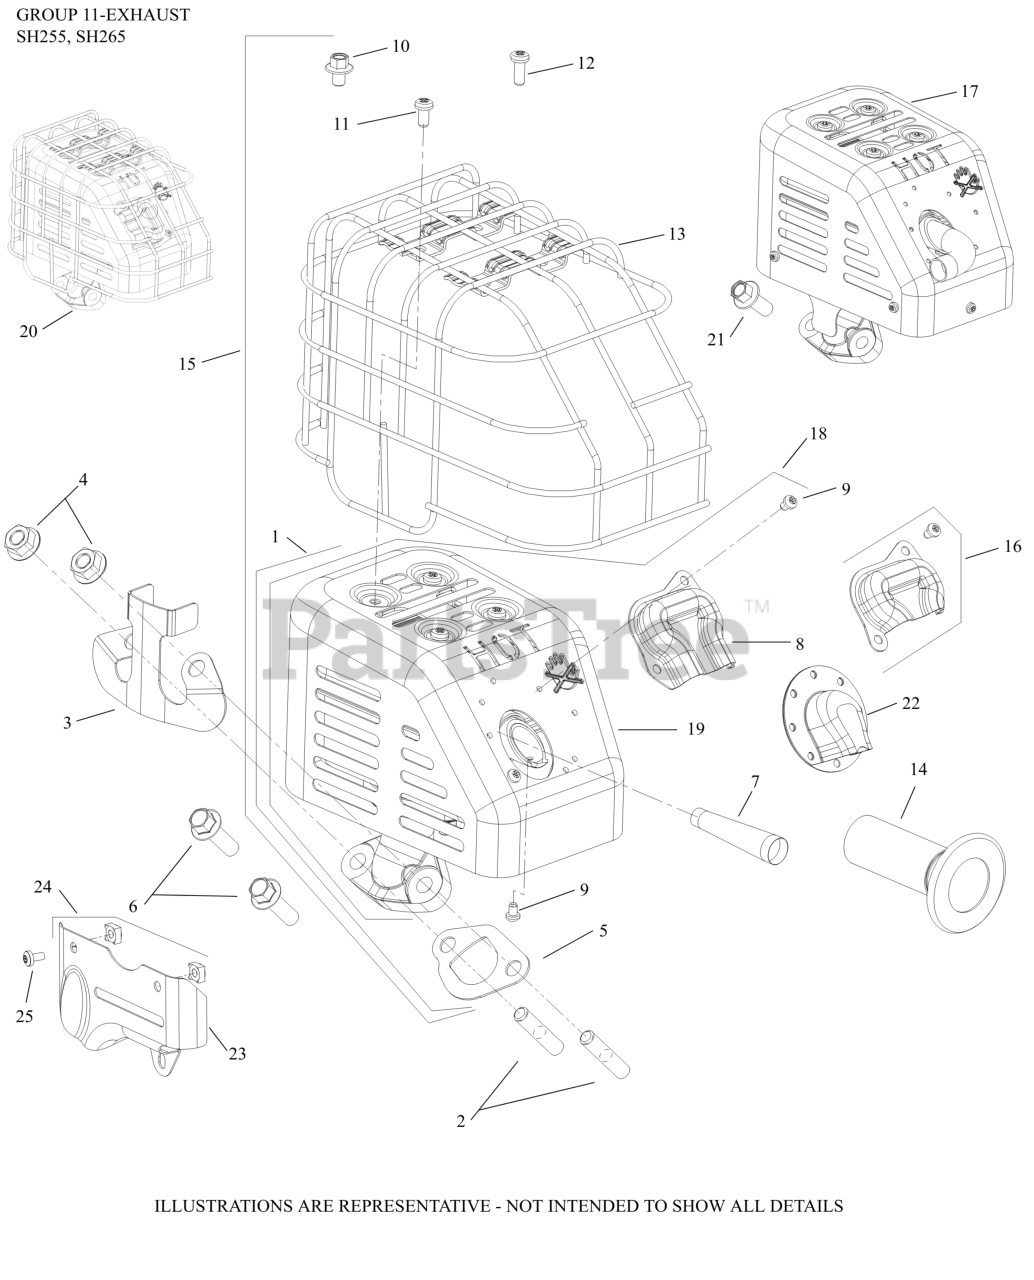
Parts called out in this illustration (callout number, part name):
1	KIT, MUFFLER
5	GASKET, EXHAUST
6	SCREW, HEX FLANGE (M8)
7	SCREEN, SPARK ARRESTOR-DISCONTINUED
8	DEFLECTOR, EXHAUST - USE 18 730 01-S
9	SCREW, SPARK ARRESTOR
12	SCREW, M5 X 10
